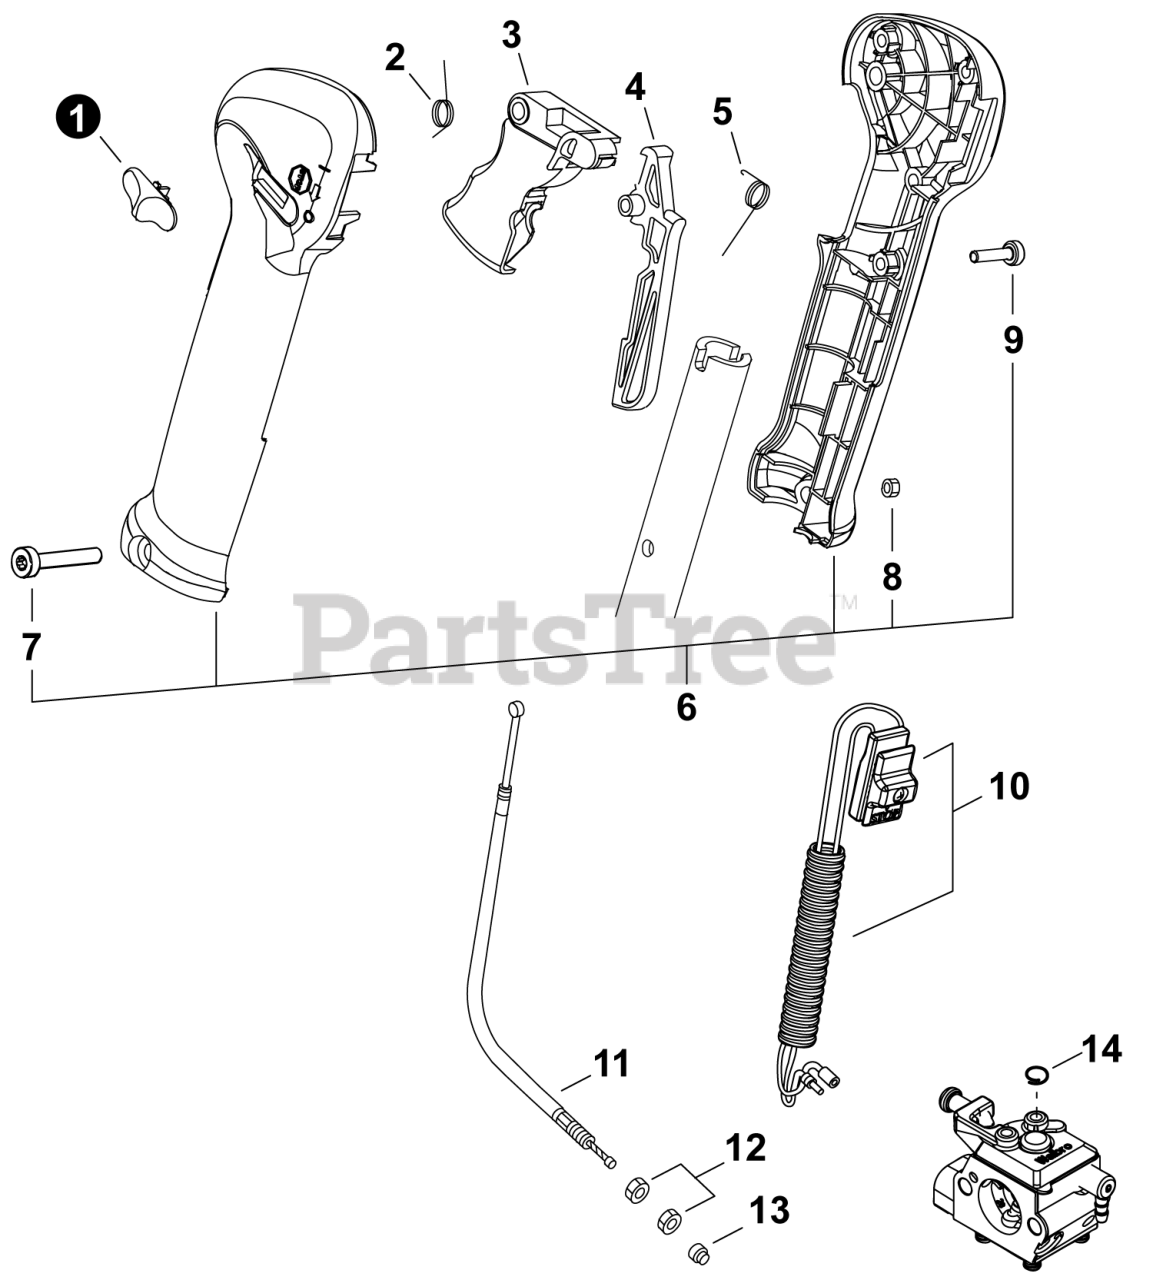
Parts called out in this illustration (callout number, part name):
1	LATCH, THROTTLE
2	SPRING, TORSION
3	CONTROL, THROTTLE
4	LOCKOUT, THROTTLE
5	SPRING, TORSION
6	GRIP SET, THROTTLE
7	BOLT, TORX 5×30
9	BOLT, TORX 4×16
10	SWITCH ASSY, ON-OFF
11	CABLE, THROTTLE
13	CAP, DUST
